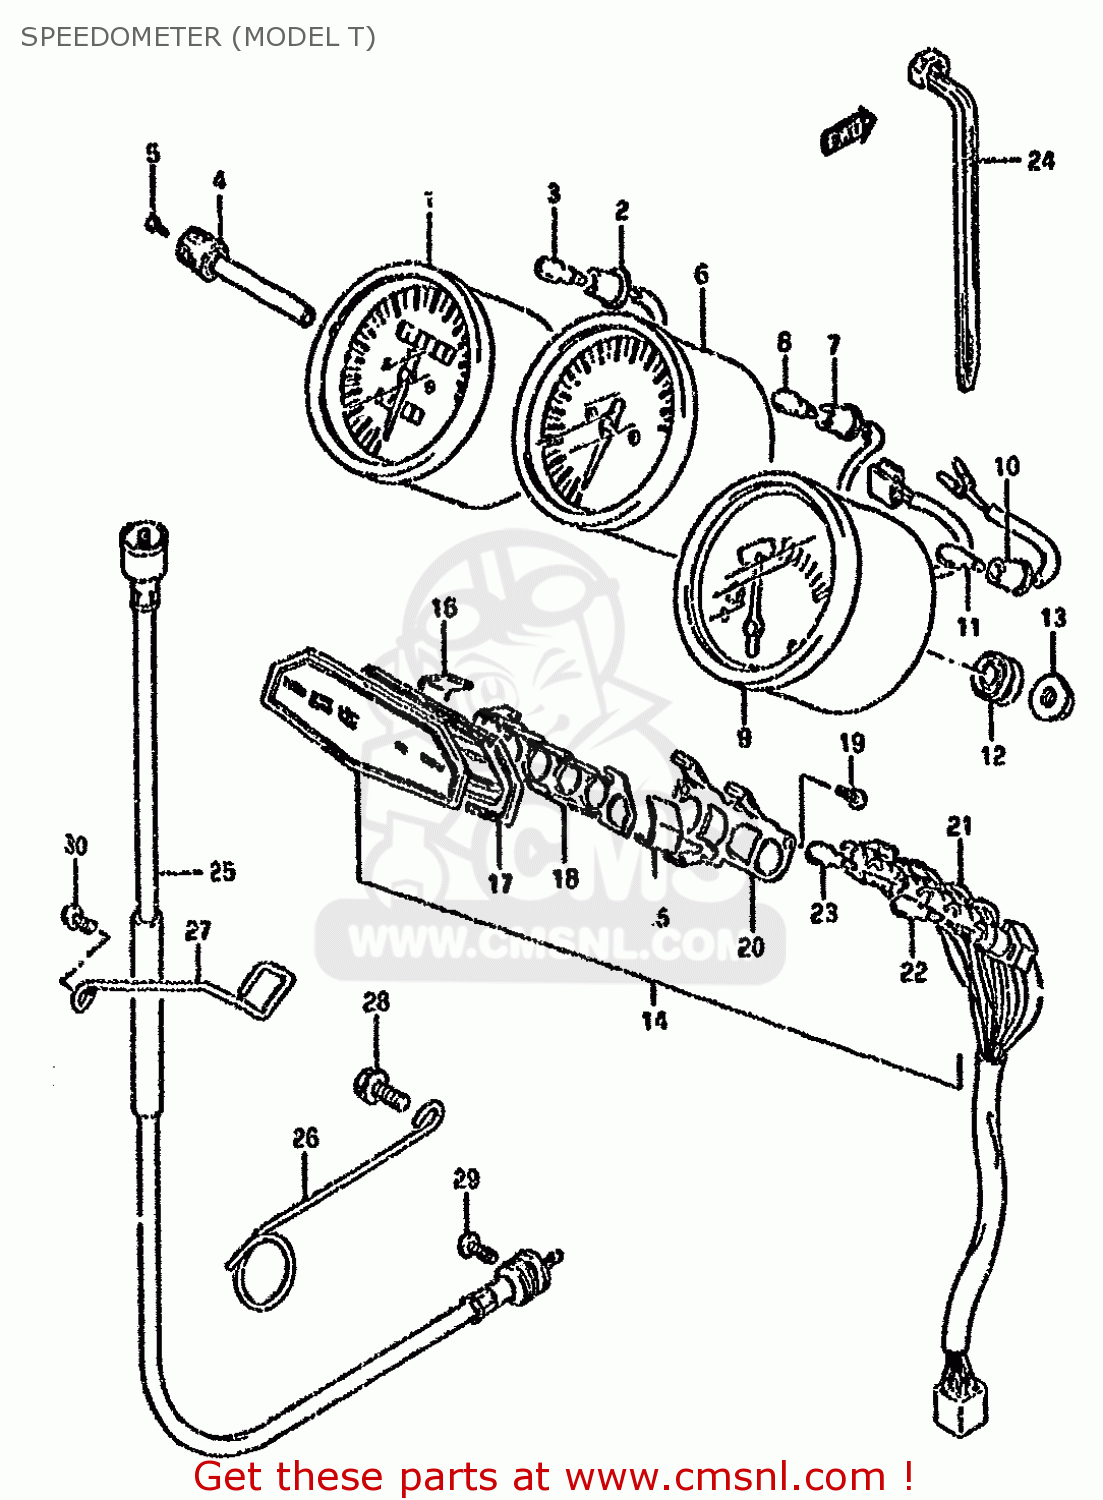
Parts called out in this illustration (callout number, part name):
1	SPEEDOMETER ASSY
2	SOCKET
3	BULB(12V3W,WB371,T7)
4	KNOB,TRIP
5	SCREW,TRIP KNOB
6	TACHOMETER ASSY
7	SOCKET
8	BULB(12V3W,WB371,T7)
9	METER ASSEMBLY,FUEL
10	SOCKET
11	BULB(12V3W,WB371,T7)
12	CUSHION
13	NUT
14	BOX ASSY
15	PLATE,TURN,R
16	PLATE,TURN,L
17	CUSHION
18	PLATE,PILOT LAMP
19	SCREW
20	LOCK PLATE
21	SOCKET
22	BULB(12V1.7W,WB372,T7)
23	BULB(12V3W,WB371,T7)
24	CLAMP(L:125)
25	CABLE ASSY,SPEEDOMETER
26	CLAMP,SPEEDOMETER CABLE
27	CLAMP,SPEEDOMETER CABLE
28	BOLT
29	SCREW
30	SCREW 5X12
